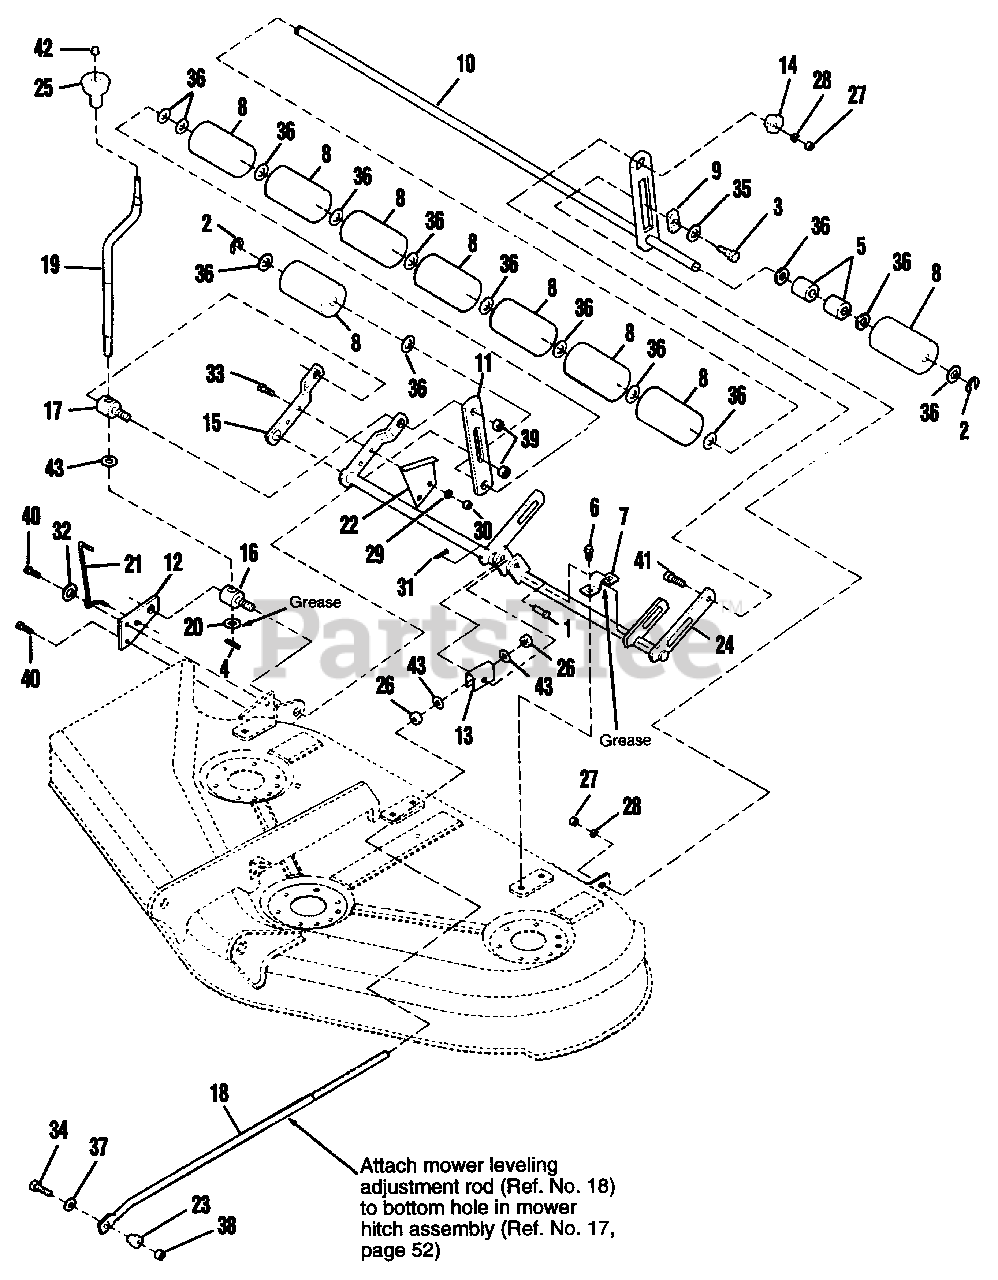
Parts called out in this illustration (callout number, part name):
1	PIN, Clevis
2	RING, Retaining
3	BOLT, Shoulder, 3/8-16 X 1.34
4	PIN, Roll, 1" Long
5	SPACER, .66 ID
6	SCREW, Hex Taptite, 5/16 x 3/4
7	STRAP, Mower Arm Assy.
10	SHAFT ASSY., Roller, 44" (Incl. Ref. Nos. 2 & 5)
11	BAR, Roller
12	PLATE, Mower Support
14	NUT, Hex Adjusting, .99 DIA .687
15	ARM, Rear, Mower, RH
17	TRUNNION, Threaded
18	ROD, Adjustment
19	CRANK, Cutting Height
20	WASHER, Detent
21	INDICATOR, Cutting Height
22	BRACKET, Cutting Height
24	ARM ASSY., Mower
25	KNOB, Height Crank
26	NUT, Hex, Jam, 1/2-13
27	NUT, Hex Hd., 3/8-16
28	LOCKWASHER
29	LOCKWASHER, 5/16
30	NUT, Hex, 5/16-18
31	COTTER PIN
32	WASHER, Flat, 5/16
33	CAPSCREW, Hex Hd., 5/16-18 x 1-1/4
34	CAPSCREW, Hex Head, 3/8-16 x 1-3/4
35	WASHER, Plain, 1/2
36	WASHER, 5/8
37	WASHER, Plain
38	NUT, Hex, Whizlock, 3/8-16
39	NUT, Hex, Flange Lock, 1/2-13
40	SCREW, Hex, Washer, Taptite, 5/16-18 x 1-1/4
41	CARRIAGE BOLT, 3/8-16 x 1-1/2
42	PAL NUT
43	WASHER, 33/64
